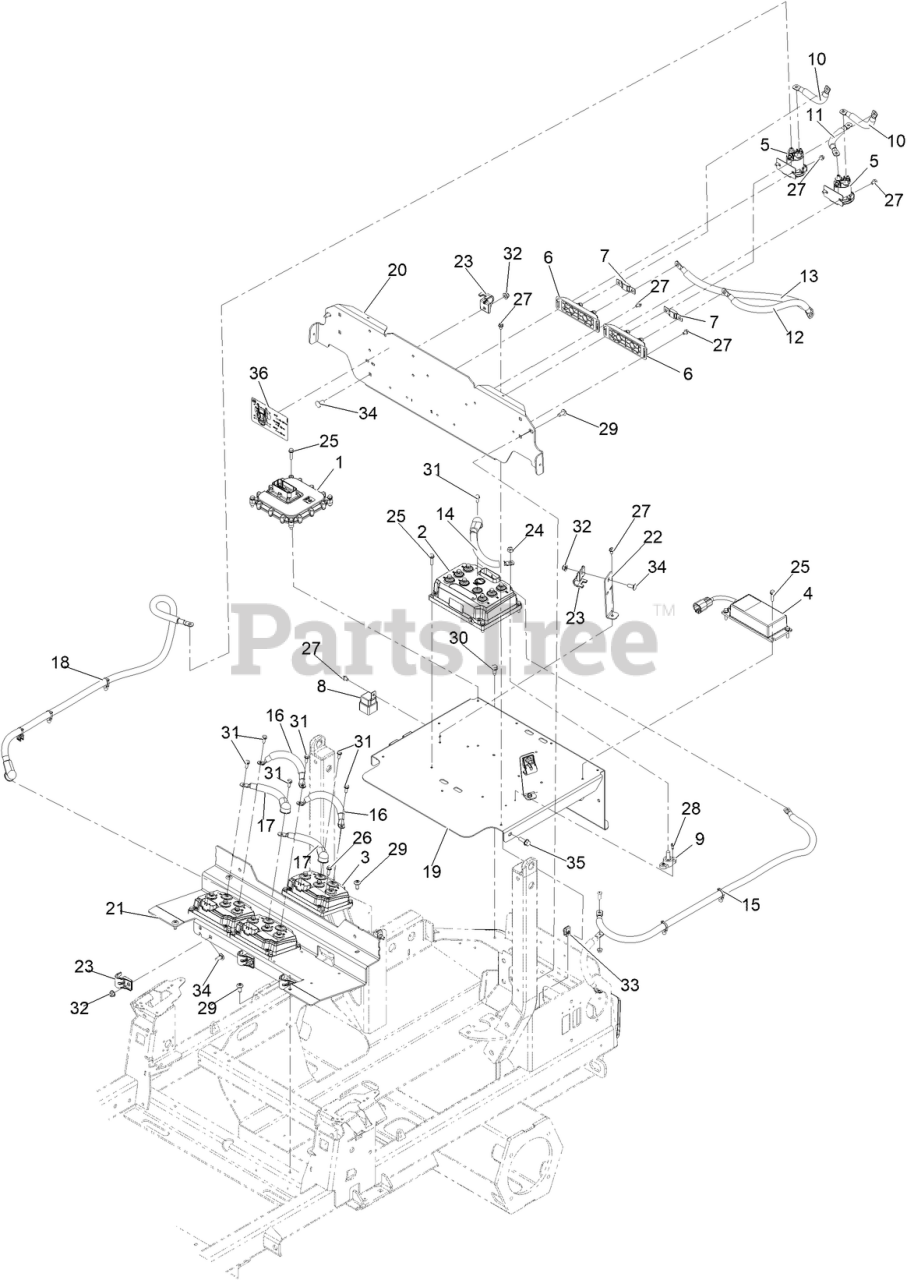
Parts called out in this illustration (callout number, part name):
1	CONTROLLER
2	INV/CTRLR-48V,DUAL 94ARMS
3	INV/CTRLR-48V
4	CONVERTER DC-DC
5	CONTACTOR-DC, 12V
6	HOLDER-FUSE
7	FUSE-200A
9	BLOCK-JUNCTION
10	CABLE-BATTERY, RD ASM
11	CABLE-BATTERY, RD ASM
12	CABLE-BATTERY, RD ASM
13	CABLE-BATTERY, RD ASM
14	CABLE-BATTERY, BK ASM
15	CABLE-BATTERY, BK ASM
16	CABLE-BATTERY, BK ASM
17	CABLE-BATTERY, RD ASM
18	CABLE-BATTERY, RD ASM
19	Bracket-Chassis
20	Plate-Firewall
21	PLATE-CONTROLLER, DECK
22	BRACKET-CABLE
23	MOUNT-CABLE
24	NUT-HEX
25	SCREW-HWHTF
26	SCREW-HWH, THREAD ROLL
27	SCREW-HWH
28	SCREW-FORMING, THREAD
30	Screw-HWH 5/16-18 X 3/4 Tf
31	SCREW-SEMS
32	NUT-HF, NI
33	NUT-CLIP, U
34	SCREW-CARR
35	SCREW-HHF
36	DECAL-SERVICE AID
